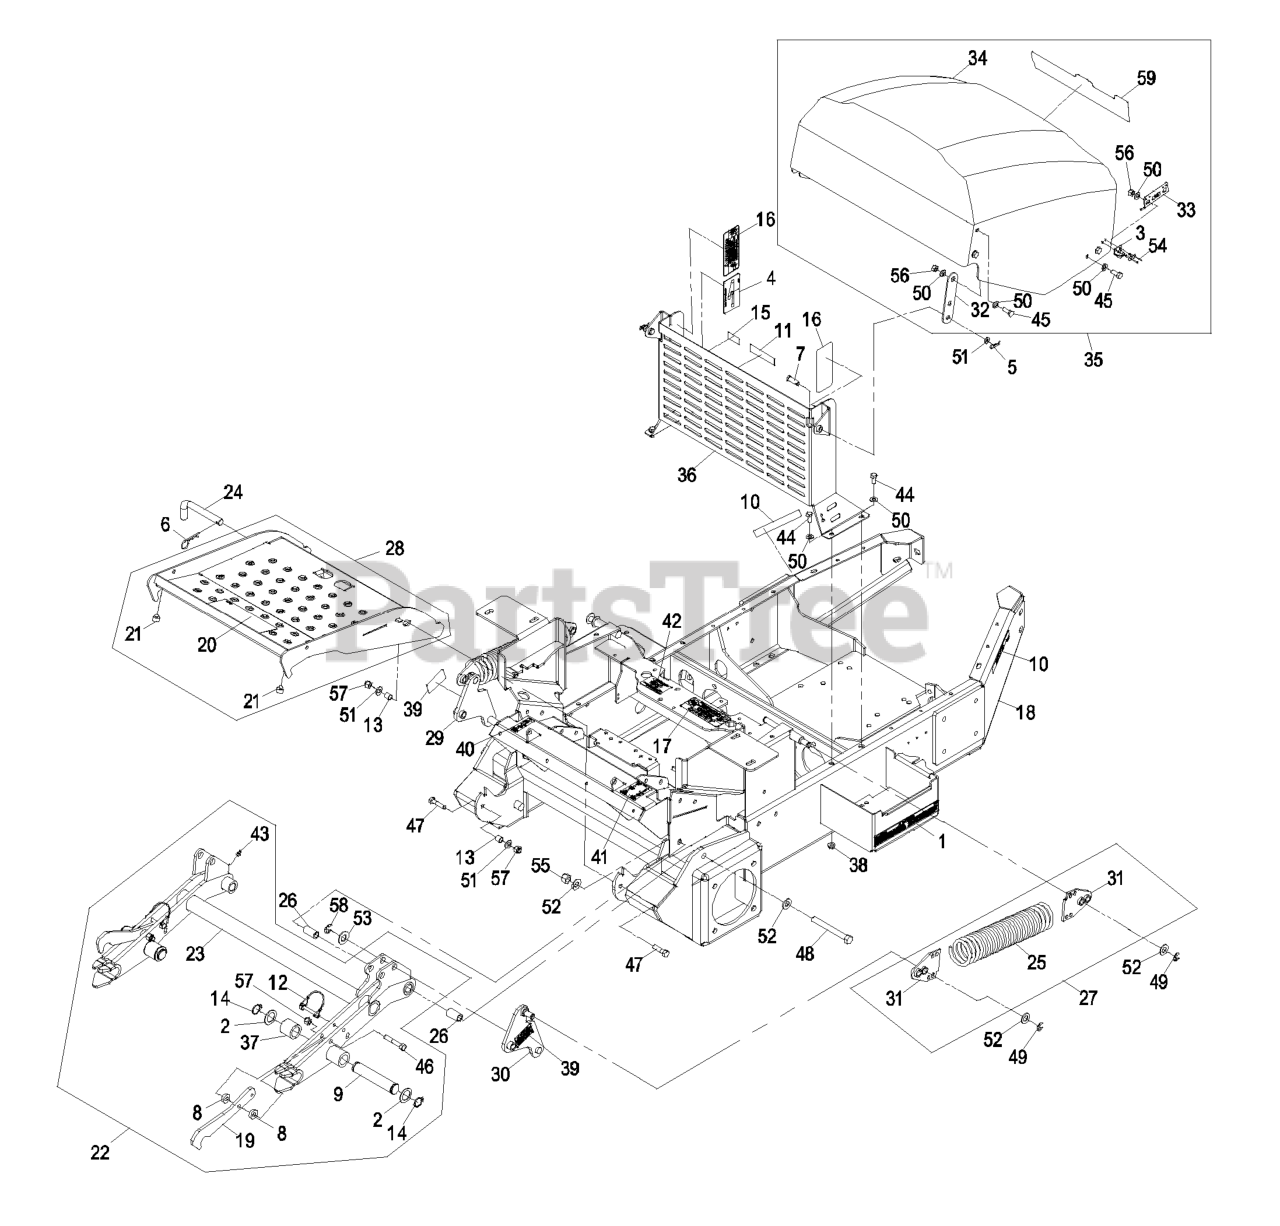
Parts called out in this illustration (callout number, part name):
1	DECAL-BATTERY
2	WASHER-SPACER
4	DECAL-ROUTING, BELT
5	PIN-COTTER
6	PIN-COTTER
7	PIN-CLEVIS
8	SPACER
10	DECAL-WARNING
11	DECAL-COVER, MISSING
12	PIN-HITCH
13	SPACER-TUBE, PUMP LINK
14	RING-RETAINING
16	DECAL-DEVICES, ROTATING
17	DECAL,PUMP FAN WARNING
18	ASM, MAIN FRAME FMZ A/C
19	LATCH, FMZ HITCH (PLATED)
20	DECAL-WARNING
21	BUMPER-RUBBER
22	ASM,HITCH FMZ
24	PIN,FULL FOLD (PLTD)
25	SPRING,EXTENSION (PLATED)
26	BUSHING,HITCH PIVOT
27	ASM,FMZ WT XFR SPRING
29	ASM,FMZ RH SPRING BELLCRA
30	ASM,FMZ LH SPRING BELLCRA
31	WLD,FMZ SPRING ANCHOR (PL
33	HOOK, HOOD
34	ASM,FMZ AC HOOD W/DCL
35	ASM,FMZ AC HOOD W/DCL COM
37	ROLLER,LOCK LEVER
39	DECAL,SPRING LOADED
40	DECAL-CONTROL, MOTION
41	DECAL,MOTION CNTL/PARK BR
42	DECAL,PUMP DRIVE RELEASE
43	FITTING-GREASE
44	SCREW-HH
45	SCREW-HH
46	SCREW-HH
47	SCREW-HH
48	SCREW-HH
49	RING-RETAINING, EXTERNAL
50	WASHER-PLAIN
51	WASHER-FLAT
52	WASHER-FLAT
53	WASHER-FLAT
55	NUT-LOCK, NI
56	NUT-LOCK, NI
57	NUT-LOCK, NI
59	DECAL,FRONTRUNNER
